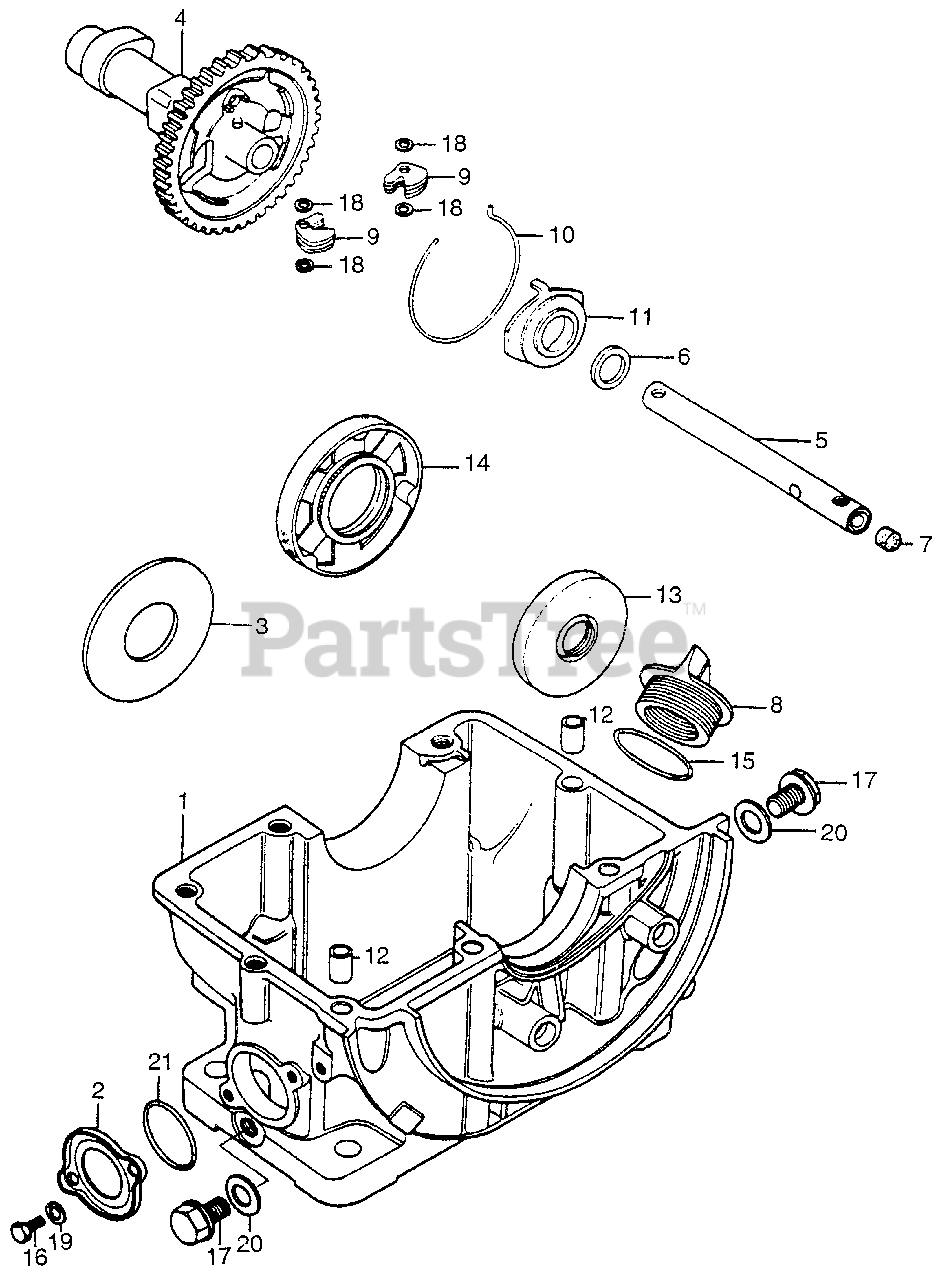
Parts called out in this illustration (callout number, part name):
2	COVER, OIL PAN
3	PLATE, GUIDE
4	CAMSHAFT (NOT AVAILABLE)
5	CENTER, CAMSHAFT (NOT AVAILABLE)
6	COLLAR, CAMSHAFT (NOT AVAILABLE)
7	PLUG, CAMSHAFT SEALING (NOT AVAILABLE)
9	WEIGHT, GOVERNOR
10	CENTER, GOVERNOR WEIGHT
11	SLIDER, GOVERNOR (NOT AVAILABLE)
12	PIN, KNOCK (8.5X11) (NOT AVAILABLE)
13	OIL SEAL (PJ20528)
14	OIL SEAL (30X65X10) (NOT AVAILABLE)
15	O-RING (26X2.7)
16	BOLT, HEX. (6X12)
17	BOLT, DRAIN PLUG (12MM)
18	WASHER, PLAIN (3MM)
19	WASHER, SPRING (6MM)
20	WASHER, DRAIN PLUG (12MM)
21	O-RING (27X2.0)
